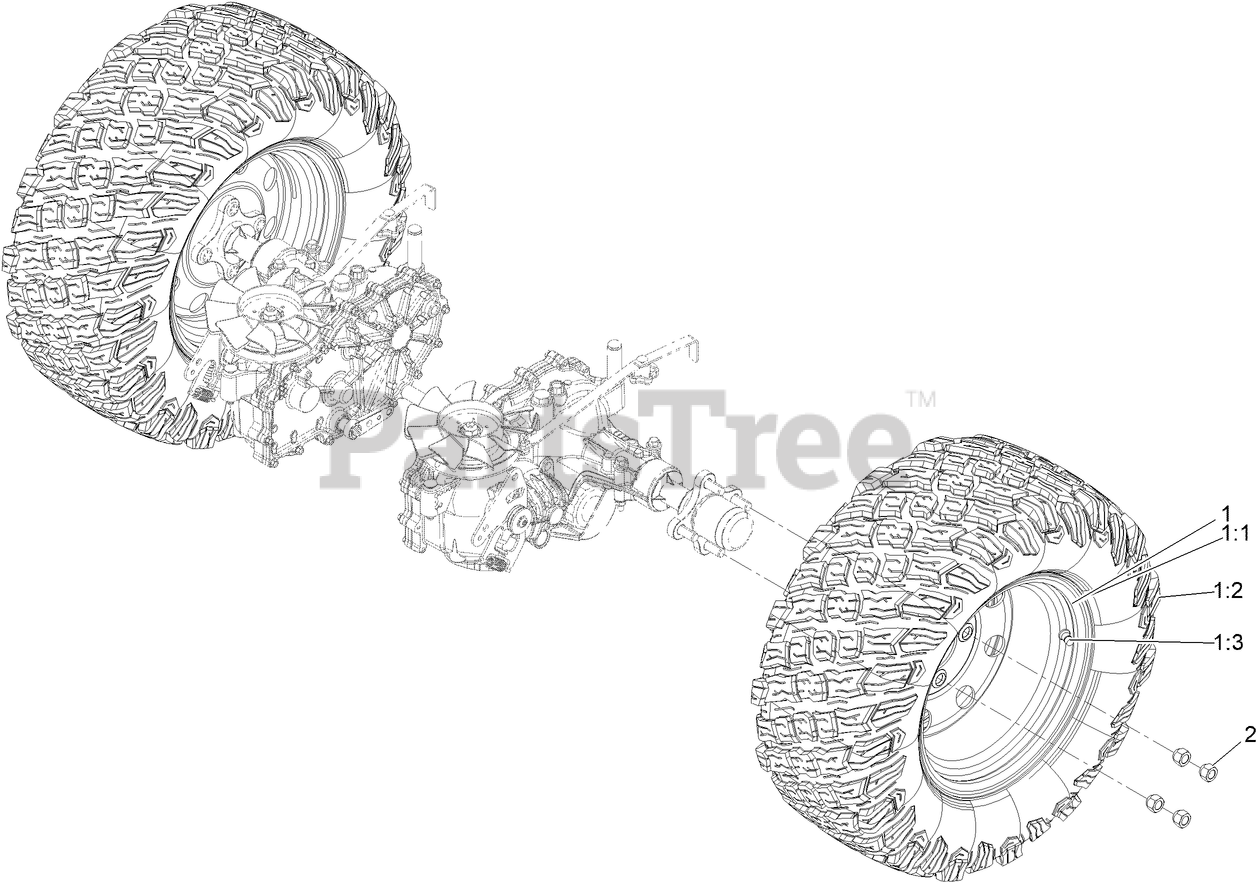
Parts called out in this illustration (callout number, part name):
1	ASM-WHEEL AND TIRE
1:2	TIRE-24X9.5-12
1:3	VALVE
2	NUT-LUG
